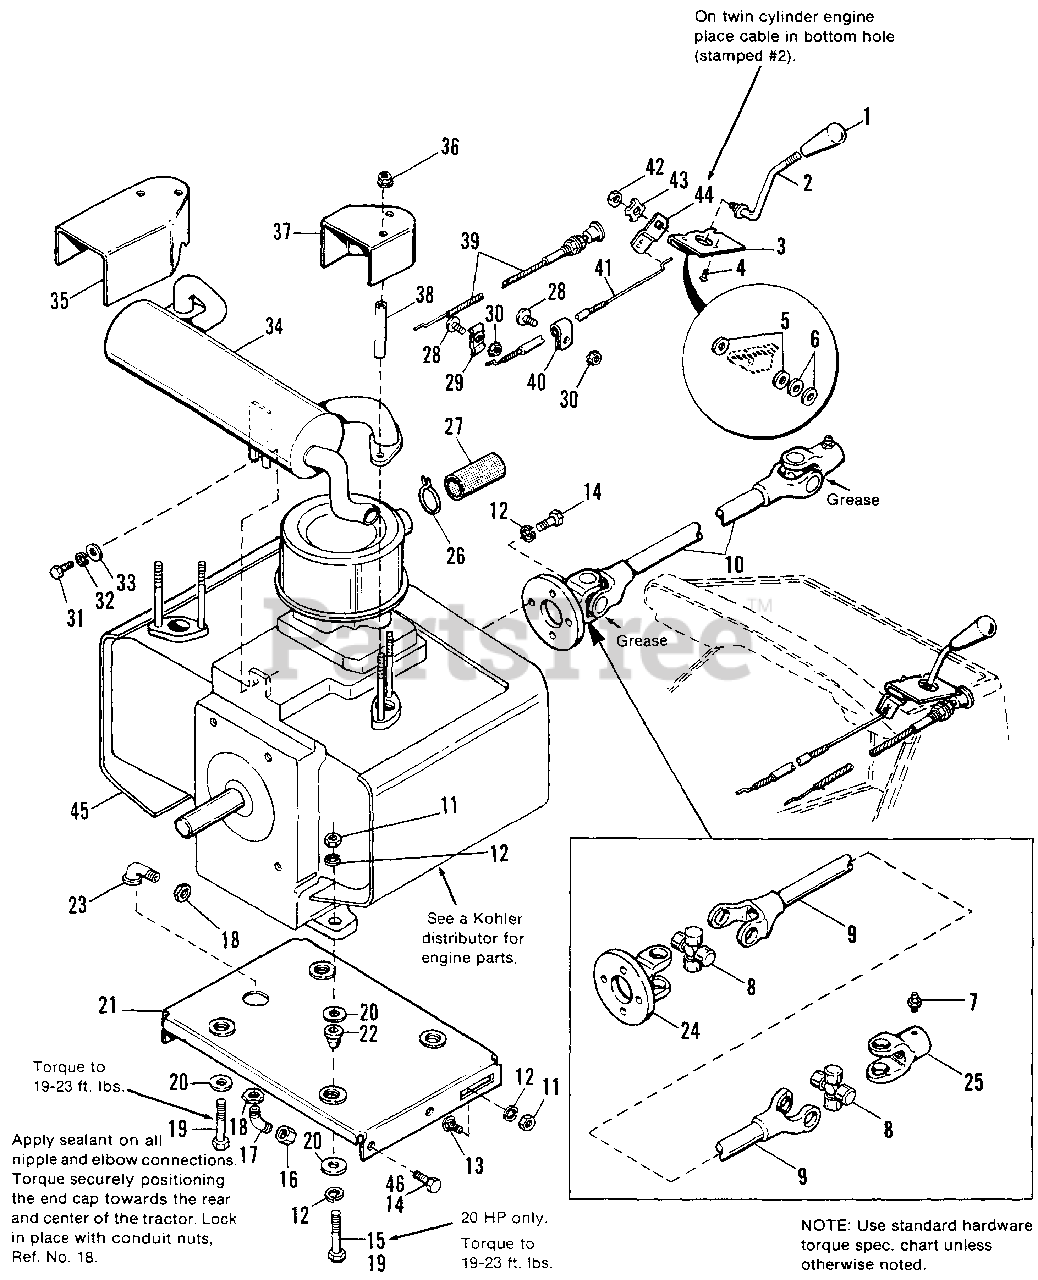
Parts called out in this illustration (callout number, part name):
1	KNOB, Tapered, 3/8-16
2	HANDLE, Throttle
3	BRACKET, Mounting, Throttle Control
4	SCREW, Hex Hd., Slotted, Plastite, 1/4-10 x 5/8
5	WASHER, Nylon, 41/64" I.D. x 1" O.D. x 1/32"
6	WASHER, Plain, 5/8" ID x 1" OD x 1/64"
7	FITTING, Lube
8	JOURNAL ASSY. (Incl. E-Clips & Grease Fittings)
8	CROSS & BEARING KIT (Weasler)
9	YOKE & TUBE ASSY. (Neapco)
9	YOKE & TUBE ASSY. (Weasler)
10	DRIVE SHAFT ASSY. (Incl. Ref. Nos. 7, 8, 9, 24 & 25)
11	NUT, Hex, 318-16 (Qty. 6 on 20 HP)
12	LOCKWASHER, 3/8
13	BOLT, Carriage, 3/8-16 x 7/8
14	CAPSCREW, Hex Hd., 3/8-16 x 1 (Qty. 5 on 1691017, 1691018)
15	CAPSCREW, Hex Hd., 3/8-16 x 1-3/4 (20 HP only)
16	CAP, Hex, 318-18
17	DRAIN, Oil
18	NUT, Conduit, 3/8-18
19	CAPSCREW, Hex Hd., 318-16 x 2 (Qty. of 3 on 20 HP)
20	WASHER, Plain, 13/32 x 1-1/2 x 1/8 Thick
21	PLATE ASSY., Engine Base
22	MOUNT, Engine
23	FITTING, 90, 3/8
24	YOKE & FLANGE ASSY. (Neapco)
24	YOKE & FLANGE ASSY. (Weasler)
25	YOKE (Neapco)
25	YOKE (Weasler)
26	CLAMP, Self Tightening
27	INTAKE, Air
28	SCREW, Truss Hd. (Phillips), #10-32 x 1/2
29	CLIP, Double
30	NUT & WASHER ASSY., #10-32 (KEPS)
31	CAPSCREW, Hex Hd., 1/4-20 x 7/8
32	LOCKWASHER, 1/4
33	WASHER, Plain, 1/4
34	MUFFLER, Exhaust (1691017, 1691018 only)
34	MUFFLER, Exhaust (all except 1691017, 1691018)
35	COVER, Manifold, R.H.
36	NUT, Flange, Lock, 5/16-18
37	COVER, Manifold, L.H.
38	SPACER, Manifold Cover
39	CONTROL, Choke w/Knob
40	CLIP, Bowden, Wlre, 3/16
41	CABLE, Throttle
42	LOCKNUT, Hex, 3/8-16
43	LOCKWASHER, Dished, 3/8
44	ARM, Throttle
45	ENGINE, 18 HP Kohler
45	ENGINE, 20 HP Kohler
46	CAPSCREW, Hex, Taptite, 3/8-16 x 1 1/4 (1691380 thru 1691953)
